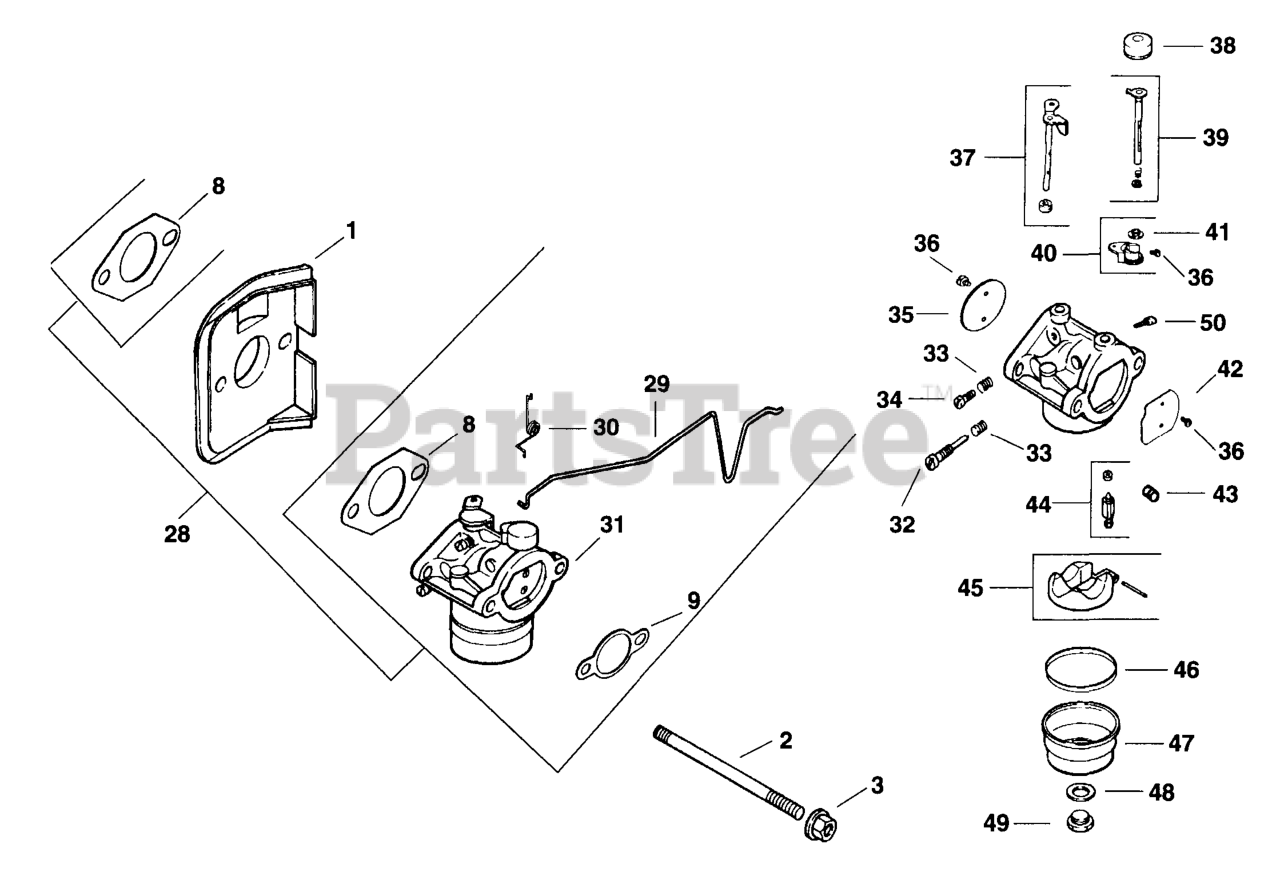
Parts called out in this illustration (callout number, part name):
1	Deflector, Heat
2	Stud, Carburetor M6x1.0x122.8
3	Nut, Hex. Flange M6x1.0
8	Gasket, Carburetor
9	Gasket, Air Filter
28	Kit, Carburetor
29	Linkage, Choke
30	Spring, Choke Return
31	Carburetor Assembly
32	Needle, Idle Fuel Adjusting
33	Spring, Idle Fuel & Idle Speed Adjusting
34	Screw, Idle Speed Adjusting
35	Plate, Throttle
36	Screw, Valve
37	Shaft, Throttle W/Lever & Seal
38	Cap, Choke Lever
39	Shaft, Choke
40	Kit, Choke Lever Repair
41	Bushing, Choke
42	Plate, Choke
43	Jet, Main
44	Needle And Seat
45	Kit, Float
46	Gasket, Bowl
47	Bowl, Fuel
48	Gasket, Bowl Retainer Screw
49	Screw, Bowl Retainer
